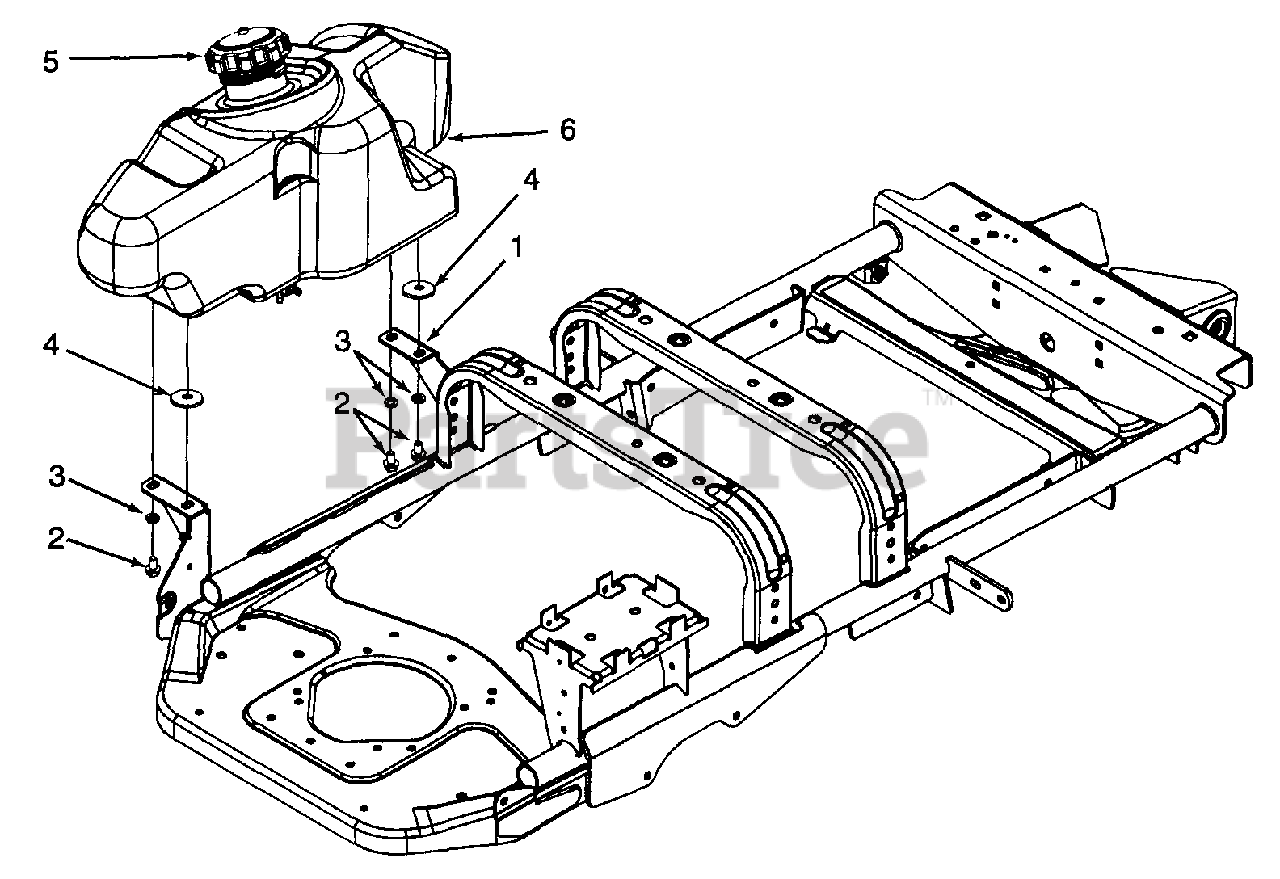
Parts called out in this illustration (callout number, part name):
3	Washer, Lock, 3/8
4	Washer, Flat, .390 x 1.5 x .10
5	Cap, Fuel
6	Fuel Tank
